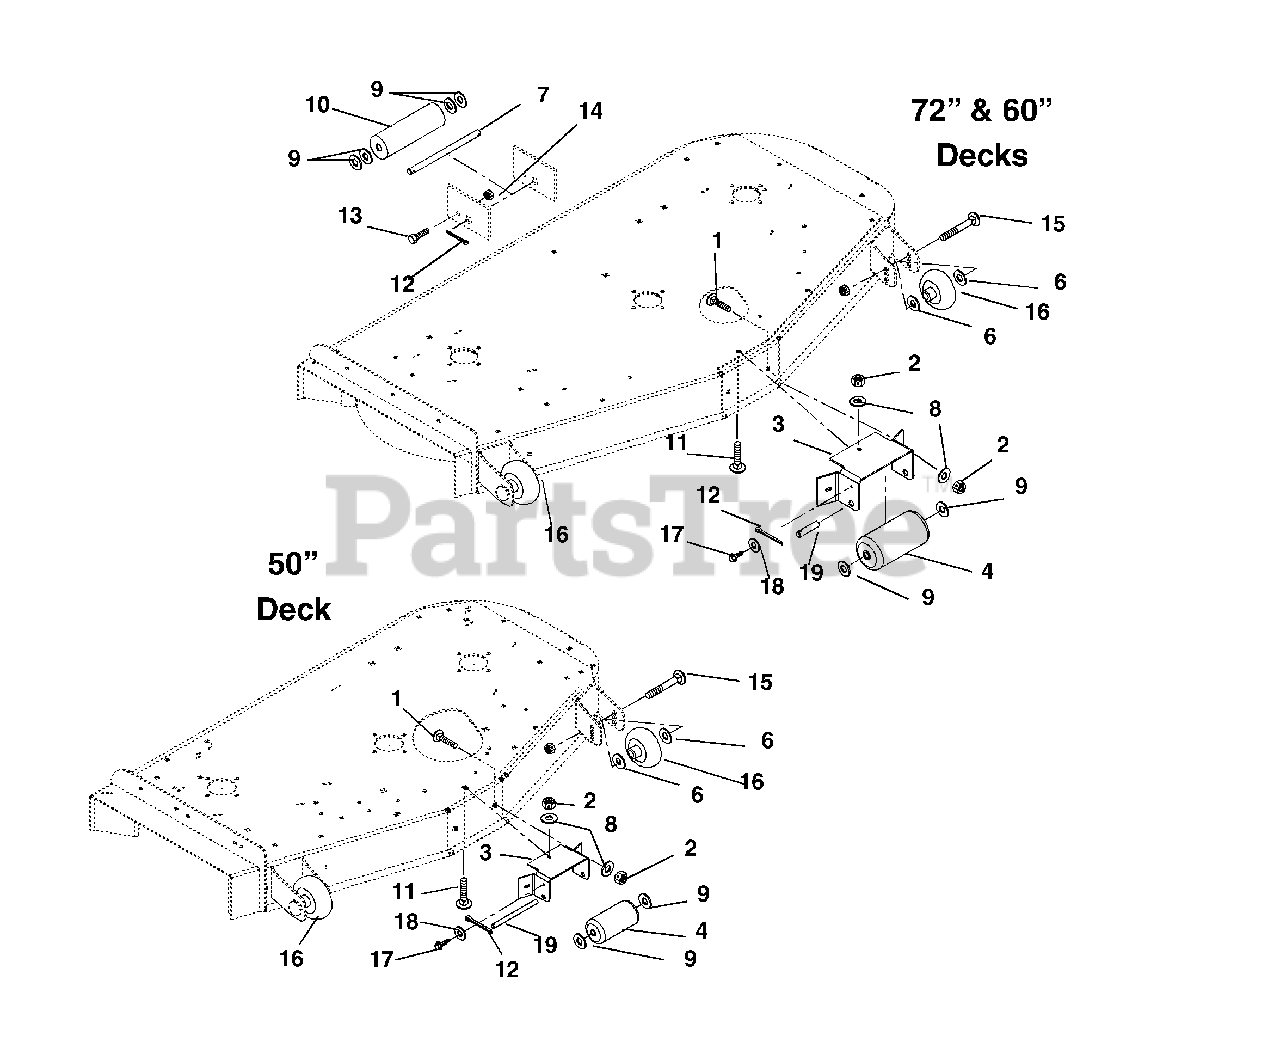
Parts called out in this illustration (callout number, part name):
1	Bolt-Round Head Square Neck .38-16 x 1.00 Grade 5)
2	Nut-Locking-Nylon .38-16
3	Bracket, Anti-Scalp Roller
5	Nut-Locking-Nylon .50-13
6	Washer-Flat-Steel .531 x 1.06 x .095
7	Shaft, Center Roller (60" & 72" Deck)
8	Washer-Flat-Steel .406 x .812 x .065
9	Washer-Flat-Steel .656 x 1.31 x .095 (72" & 60" Deck)
9	Washer-Flat-Steel .656 x 1.31 x .095 (50" Deck)
10	Roller, Gage (60" & 72" Deck)
11	Bolt-Round Head Square Neck .38-16 x 1.25 Grade 5
12	Pin-Cotter .25 x 2.00 (72" & 60" Deck)
12	Pin-Cotter .25 x 2.00 (50" Deck)
13	Bolt-Hex .25-20 x .75 Grade 5 (72" & 60" Deck)
14	Nut-Locking-Center .25-20 (72" & 60" Deck)
15	Bolt-Round Head Square Neck .50-13 x 5.00 Grade 2
16	Wheel, 3 x 5
17	Screw-Self Tapping .25-20 x .50 x Hex Washer Head
18	Washer-Flat-Steel .281 x .62 x .065
